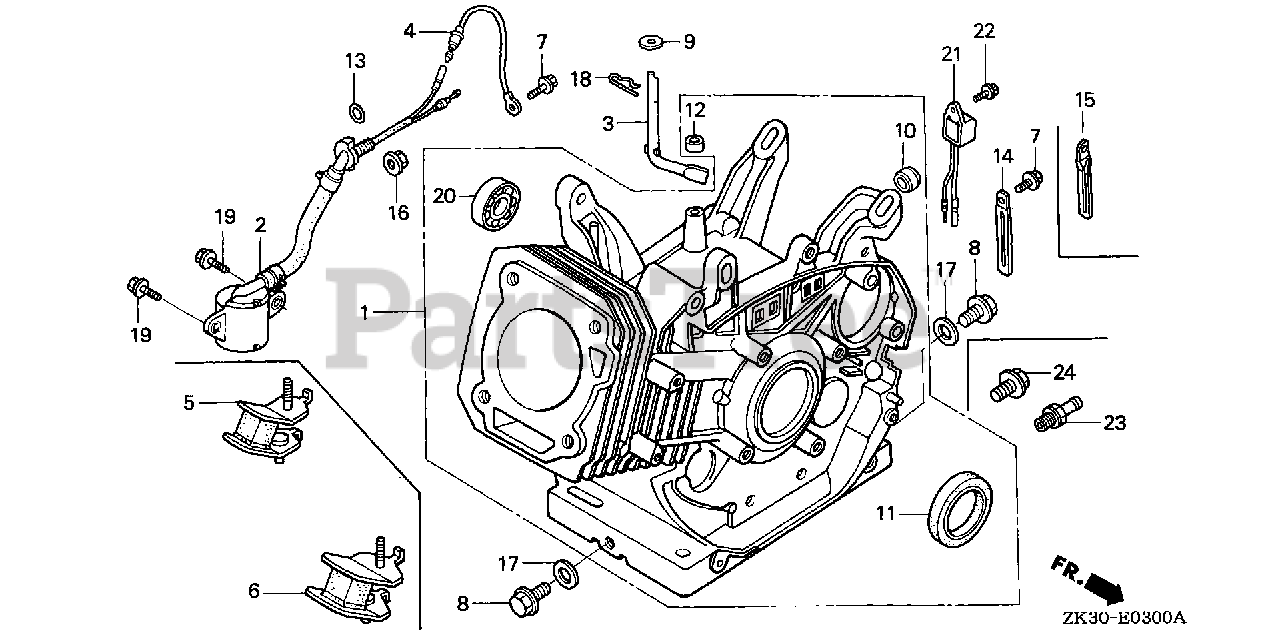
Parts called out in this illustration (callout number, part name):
1	CYLINDER ASSY. (ALERT)
2	SWITCH ASSY., OIL LEVEL
3	SHAFT, GOVERNOR ARM
4	SUB-HARNESS (NOT AVAILABLE)
7	BOLT, FLANGE (6X12) (CT200)
8	BOLT, DRAIN PLUG (12X15)
9	WASHER (8.2X17X0.8)
10	PLUG, SEALING (RUBBER 10MM)
11	OIL SEAL (35X52X8)
12	OIL SEAL (8X14X5)
13	O-RING (14MM) (ARAI)
13	O-RING (14MM) (NOK)
16	NUT, FLANGE (10MM)
17	WASHER, DRAIN PLUG (12MM)
18	PIN, LOCK (10MM)
19	BOLT, FLANGE (6X12)
20	BEARING, RADIAL BALL (6202)
21	ALERT UNIT, OIL
22	BOLT, FLANGE (6X12) (CT200)
